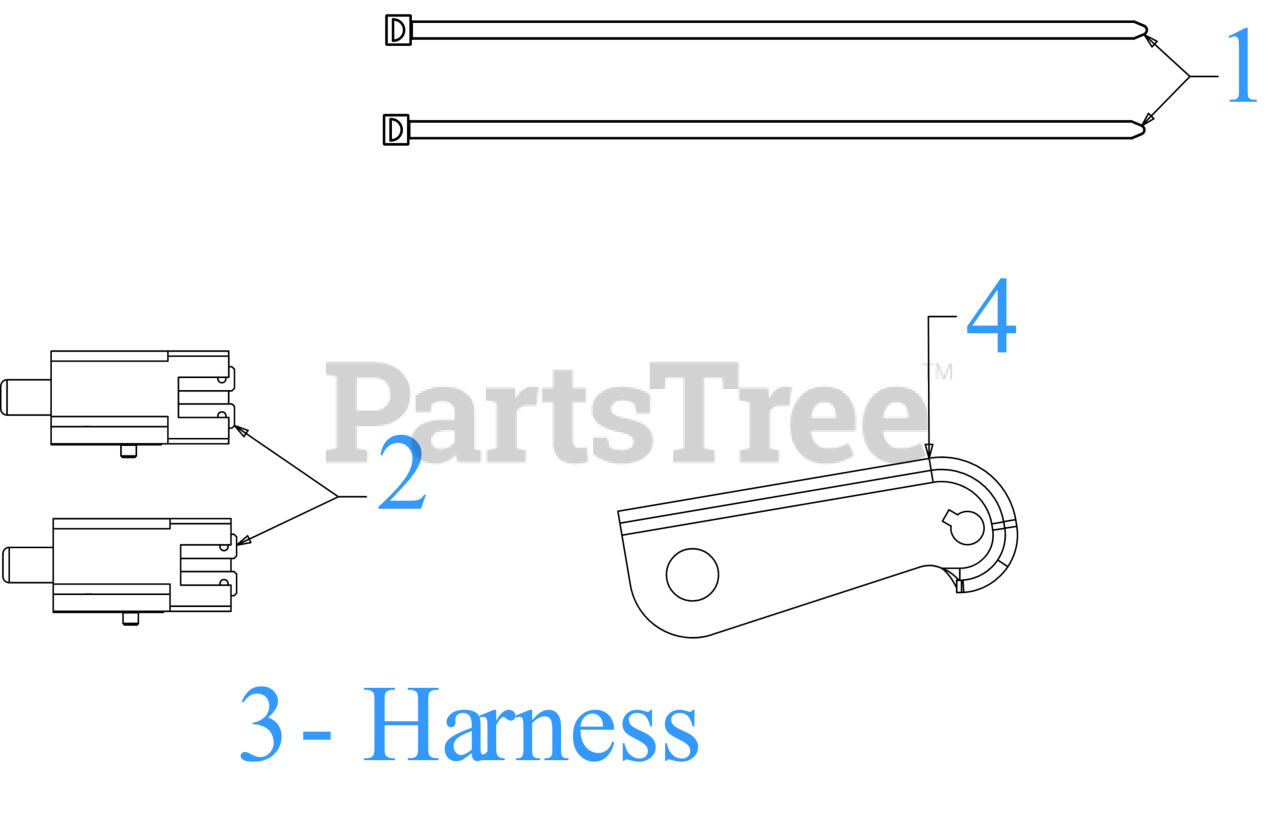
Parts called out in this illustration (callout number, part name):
1	7" CABLE TIE
2	INTERLOCK SWITCH (NO/NC)
3	MAIN HARNESS (RMC/MPTO/BULB/AGM)
3	12V SOLENOID
4	LATCH SPEED BRACKET
